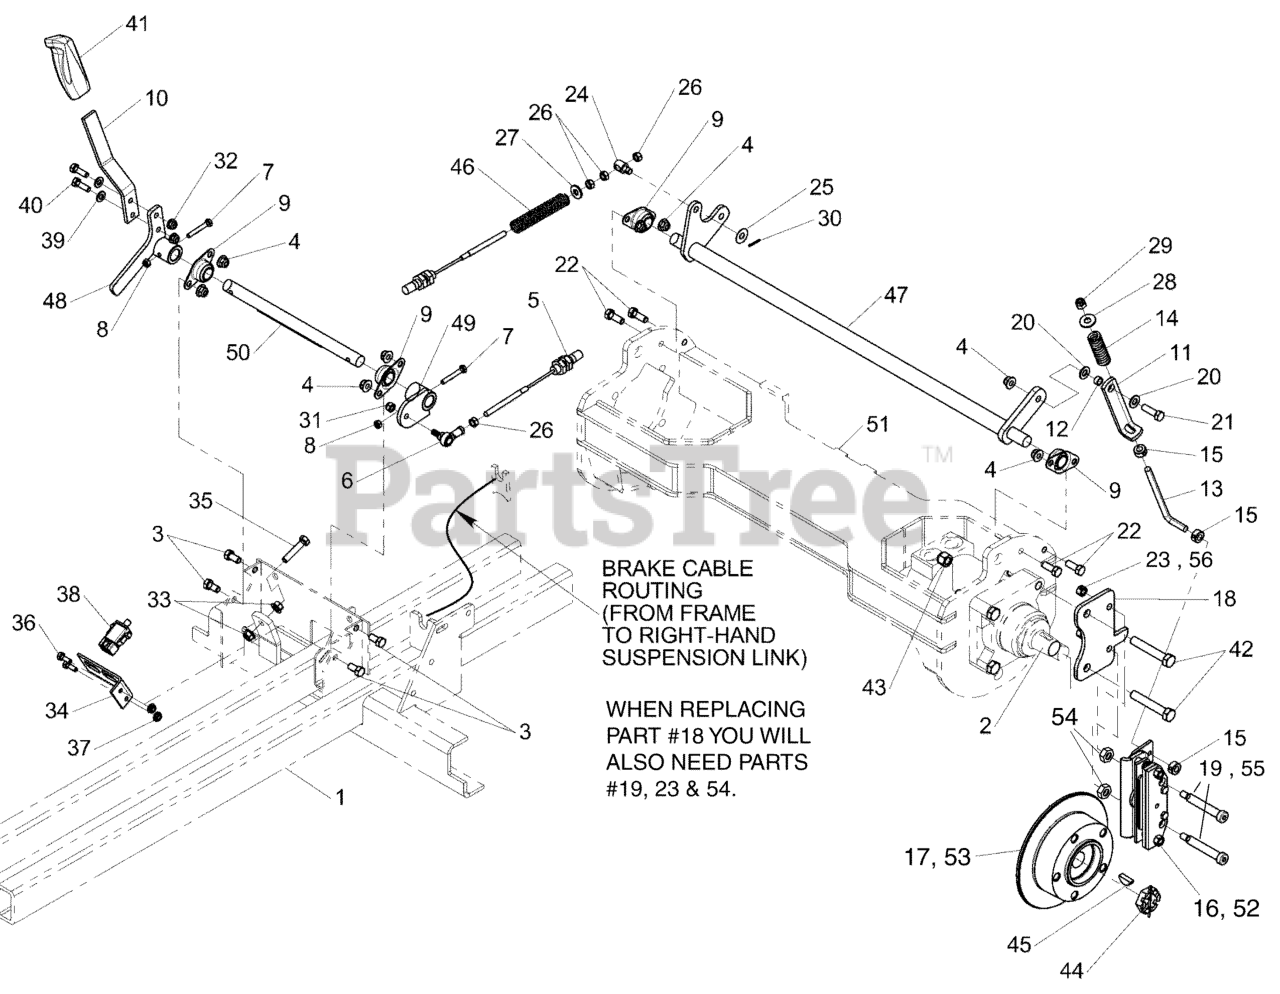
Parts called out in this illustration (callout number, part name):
1	MAIN FRAME
2	WHEEL MOTOR
3	BOLT, 3/8-16 X 3/4" GD5 CZ
4	NUT, 3/8-16 HEX NYLOCK FLANGE
5	CABLE, PARKING BRAKE - IS4500
6	JOINT, Ball
7	BOLT, 1/4-20 X 1-1/2", GD5
8	NUT, 1/4-20 HEX SIDE LOCK
9	BEARING, BRONZE FLANGE, 3/4
10	HANDLE, BRAKE
11	LINK, BRAKE LOCK - BLK
12	SPACER, .38 X .50 X .27
13	ROD, BRAKE ADJUSTMENT
14	SPRING, BRAKE
15	COLLAR, 3/8" SET
16	CALIPER, MECHANICAL, BRAKE
17	WHEEL HUB, COMPACT CALIPER (86720)
18	MOUNT, BRAKE CALIPER
19	BOLT, 1/2-13 X 4" GD5 CZ
20	WASHER, 3/8 SAE
21	BOLT, 3/8-16 X 1-1/4" GD5 CZ
22	BOLT, 3/8-16 X 1" GD5 CZ
23	NUT, 1/2-13 HEX NYLON LOCK
24	ADJUSTER, BRAKE LINKAGE
25	WASHER, .389 X 1.00 X .020, SS
26	NUT, 5/16-24 HEX
27	WASHER, 5/16" FENDER
28	WASHER, 3/8" USS
29	NUT, 3/8-16 HEX NYLON LOCK
30	PIN, 3/32 X 0.750, COT, ZINC/CLEAR
31	NUT, 5/16-24 HEX NYLON LOCK
32	NUT, 5/16-18 HEX NYLOCK FLANGE
33	NUT, 3/8-16 HEX SERRATED FLANGE
34	BRACKET, SWITCH MOUNT
35	BOLT, 3/8-16 X 2" GD5 TFL CZ
36	HHCS, 1/4-20 X 0.625, GR5, ZINC/CLEAR
37	NUT, 1/4-20 HEX SERR. FLANGE
38	SWITCH, DP NO/NC SNAP-IN
39	WASHER, 5/16" SAE
40	BOLT, 5/16-18 X 1" GD5 YZ
41	GRIP, BLACK FLEXIBLE
42	BOLT, 1/2-20 X 3" GD5 YZ
43	NUT, Hex, Nylon Lock, 1/2-20
44	NUT & COTTER PIN
45	KEY
46	SPRING, COMPRESSION, 5-1/2"
47	WELD, BRAKE SHAFT
48	WELD, BRAKE LINK
49	WELD, PIVOT LINKAGE MOUNT
50	WELD, SHAFT, BRAKE LEVER - RED
51	REAR END ASSEMBLY
52	COMPACT CALIPER, AUSCO
53	WHEEL HUB, COMPACT CALIPER (86720)
54	NUT, 1/2-13 HEX JAM
55	BOLT, 3/8-16 x 2-3/4, 1/2 SHOULDER
56	NUT, 3/8-16 HEX SIDE LOCK
